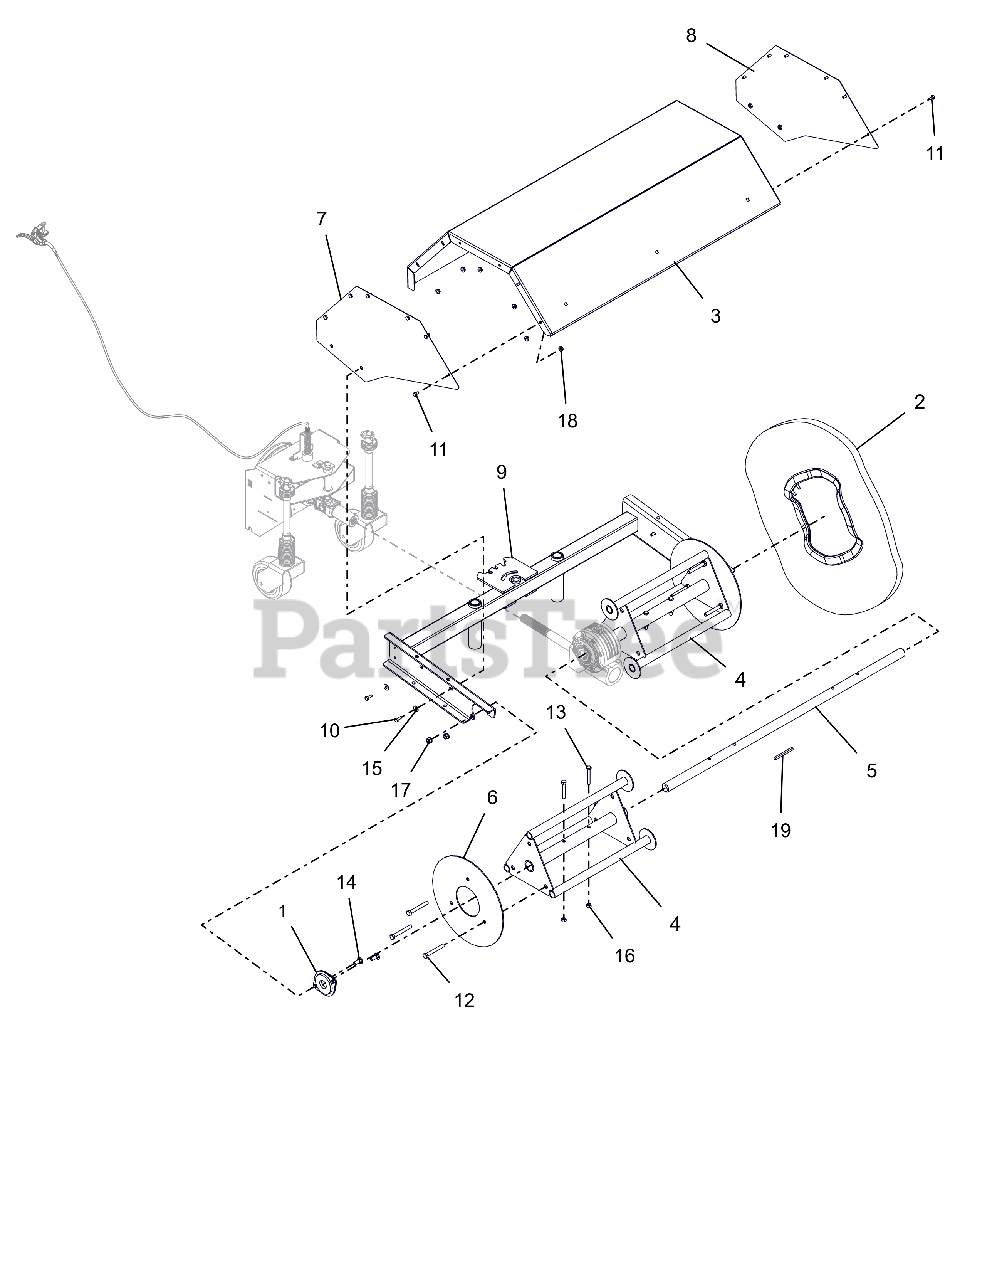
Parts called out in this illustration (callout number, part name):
1	BEARING,2 BOLT FLANGE 1-1/8 ID
2	KIT, BRISTLE - SET OF 18
3	COVER, TOP - 36" BRUSH W/DECAL
4	PB36 DRIVE CORE SERVICE KIT
5	CENTER, SHAFT
6	PLATE, END RETAINER
7	WLDT, SIDE COVER - RH
8	WLDT, SIDE COVER - LH
9	FRAME, POWER BROOM 36"
10	BLT, HEX .25-20X.75 G5 ZCC
11	BLT,HEX .25-20X.50 G5 ZCC
12	BLT, HEX .38-16X3.00F G5 ZCC
13	BLT, HEX .31-18X2.25 G5 ZCC
14	BLT, RHSN .38-16X1.00 G5 ZCC
15	WSHR, FLT .312X.734X.065 ZCC
16	NUT,LK-CTR .31-18 GA ZCC
17	NUT-LK-TOP-FLG .38-16 ZC120
18	NUT-LK-TOP-FLG .250-20 GF ZCC
19	KEY .25 X .25 X 3IN
